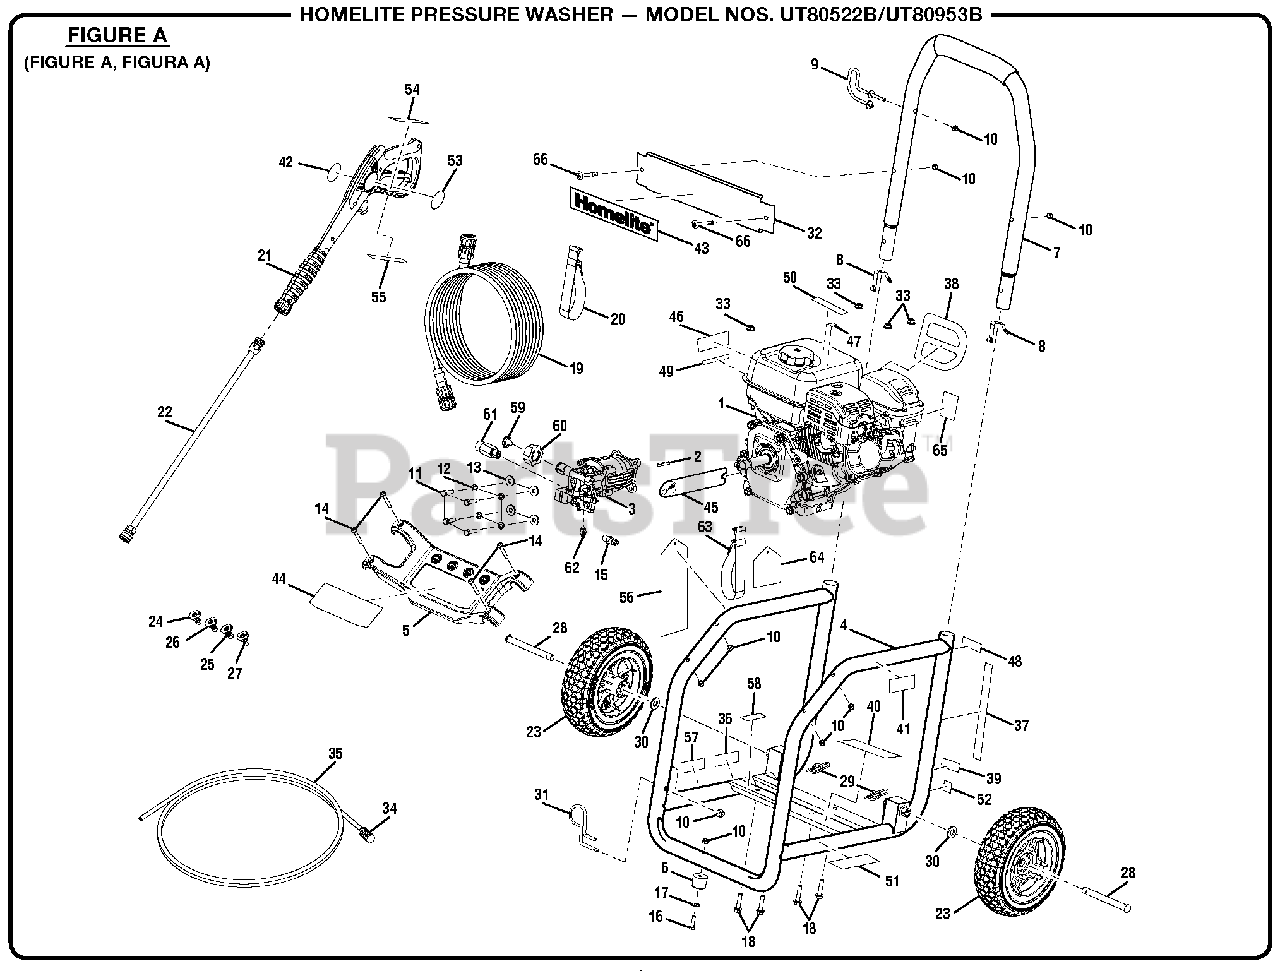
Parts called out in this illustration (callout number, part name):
1	Engine
2	Output Shaft Key (3/16 x 40 mm)
3	Pump
4	Main Frame
5	Nozzle Holder
6	Rubber Foot
7	Handle Assembly
8	Lock Button w/Spring Clip
9	Wand Holder (Upper)
10	Lock Nut (1/4-20)
11	Bolt (5/16-24 x 27 mm, Hex Hd.)
12	Lock Washer (5/16 in.)
13	Washer (5/16 in.)
14	Screw (1/4-20 x 2.0 in.
15	Thermal Release Valve
16	Bolt (1/4-20 x 1-1/4 in.)
17	Washer (1/4 in.)
18	Bolt (M8 x 40 mm, Hex Flange Hd.)
20	Hook and Loop Strap
21	Trigger Handle
22	Extension Wand
23	Wheel Assembly (10 in. x 3 in.)
24	Nozzle, 0deg
25	Nozzle 40deg
26	Nozzle 25deg
27	Soap Nozzle
29	Hitch Pin
30	Washer (1/2 in.)
31	Wand Holder (Lower)
32	Front Panel
33	Lock Nut (M8 x 1.25)
35	Chemical Siphon Tube
36	Pump Start Label
37	Engine Start Label
38	Recoil Label
39	Choke Label
40	Data Label
41	Hot Surface Label
42	Trigger Handle Logo Label
43	Homelite Label
44	Performance Label
45	Add Oil Label
46	Danger Label
47	E85 Label
48	Homelite Inquiries Label
49	EMC Compliance Label
50	No Oil to Gas Label
51	Combustion Label
52	Fuel Label
53	Trigger Handle Warning Label (French and Spanish)
54	Warning Label
55	Wand Label (Max Rating)
56	Danger Hangtag
57	Lubricant Label
58	Dip Stick Label
59	Filter Screen
60	Inlet Tube
61	Outlet Tube
62	Detergent Suction Kit
63	Hook and Loop Strap
64	Nozzle Instructions Hangtag
65	Engine Label (On-Off)
66	Screw (1/4-20 x 1.57 in., Torx T-30)
